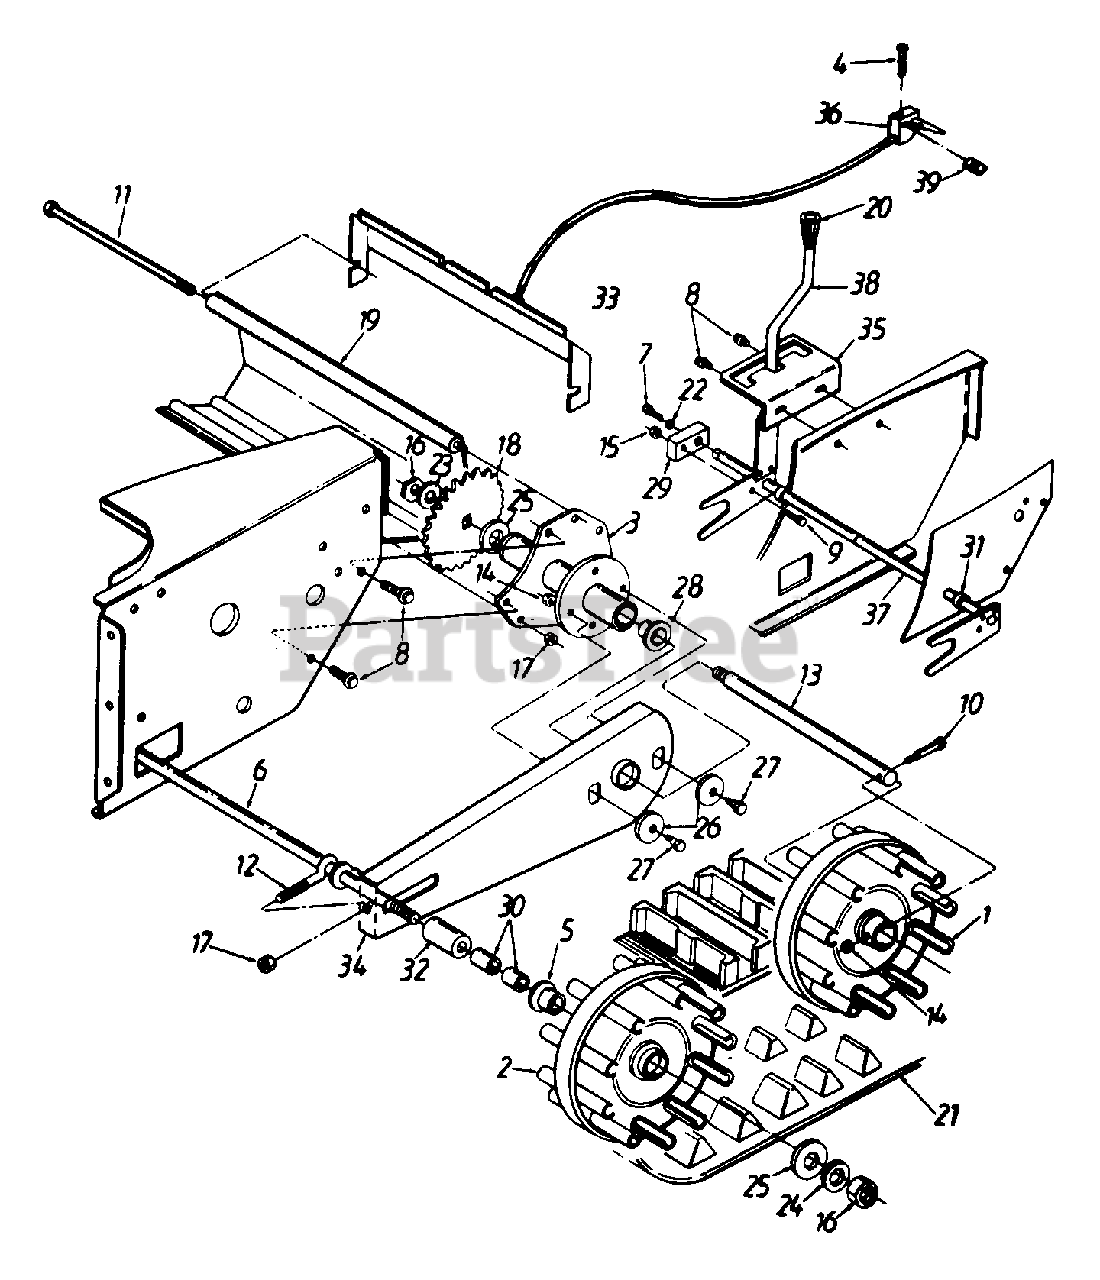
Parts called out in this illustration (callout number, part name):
1	Drive Wheel Ass'y.
2	Idler Wheel Ass'y.
4	Oval C-Sunk Hd. Scr. 10-24 x 1.375" Lg.
5	Flange Bearing 3/4" I.D. x 15/16" Lg.
7	Hex Bolt 5/16-24 x .75" Lg.
8	Hex Wash. TT-Tap Scr. 5/16-18 x .62" Lg.
9	Hex Bolt 3/8-24 x 1.5" Lg.
10	Bolt 5/16-18 x 1.5" Lg.
11	Hex Bolt Ass'y. 5/16-18 x 9.81" Lg.
12	Eyebolt 5/16-18 x 3" Lg.
13	Drive Axle
14	Hex Cent. L-Nut 5/16-18 Thd.
15	Hex Cent. L-Nut 3/8-24 Thd.
16	Hex Ins. Jam L-Nut 1/2-20 Thd.
17	Hex L-Nut 5/16-18 Thd.
18	24 Tooth Sprocket
19	Track Housing
21	Snow Track
22	L-Wash. 5/16" I.D.
23	Bell-Wash. .515" I.D. x 1.14" O.D.
24	Fl-Wash. .531" I.D. x 1.25" O.D.
25	Fl-Wash. .793" I.D. x 1.24" O.D.
26	Fl-Wash. 3/8" I.D. x 7/16" O.D.
27	Shld. Bolt .437" Dia. x .162
28	Flange Bearing 3/4" I.D. x 15/16" Lg.
29	Lift Shaft Drive
30	Spacer .5" I.D. x .78" Lg.
31	Spacer .628" I.D. x .5" Lg.
32	Spacer .51" I.D. x 1.34" Lg.
36	Track Steer Cable w/Trigger
39	Flat Weld Nut #10-24 Thd.
